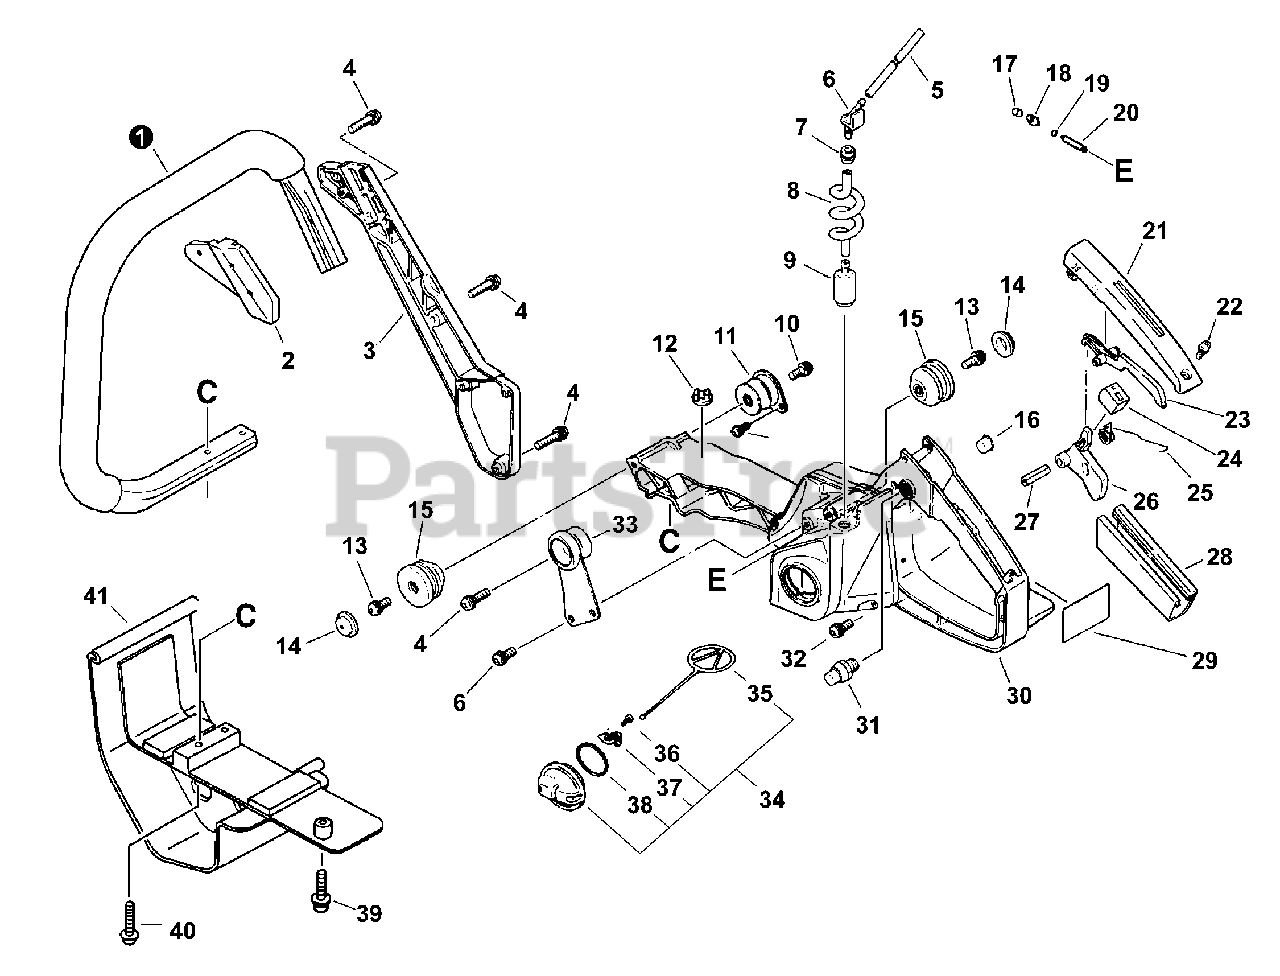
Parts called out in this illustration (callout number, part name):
1	HANDLE, FRONT
2	BRACKET, HANDLE - Gray
2	BRACKET, HANDLE - Orange
3	SUPPORTER, FRONT HANDLE - Gray
3	SUPPORTER, FRONT HANDLE - Orange
4	BOLT 5×20
5	PIPE, FUEL
6	CONNECTOR, PIPE
7	GROMMET
8	PIPE
9	FILTER, FUEL
10	BOLT 4×10
13	BOLT 5×14
14	CAP, CUSHION
17	VALVE, CHECK
18	COVER, VENT
20	PIPE - 3×5×55MM
21	COVER, HANDLE
22	BOLT 4×14
23	LOCKOUT, THROTTLE CONTROL
24	CUSHION, THROTTLE
25	SPRING, THROTTLE RETURN
26	TRIGGER, THROTTLE - Gray
26	TRIGGER, THROTTLE - Orange
27	SPRING PIN 5×25
28	GRIP, HANDLE
29	LABEL, CAUTION
30	HANDLE/FUEL TANK - Gray
30	HANDLE/FUEL TANK - Orange
31	LATCH, THROTTLE
32	SCREW 4×14
34	FUEL TANK CAP ASY
35	LINK
36	SCREW 3×8
37	REATINER, LINK
38	O-RING 29
39	BOLT 5×25
40	BOLT 5×30
